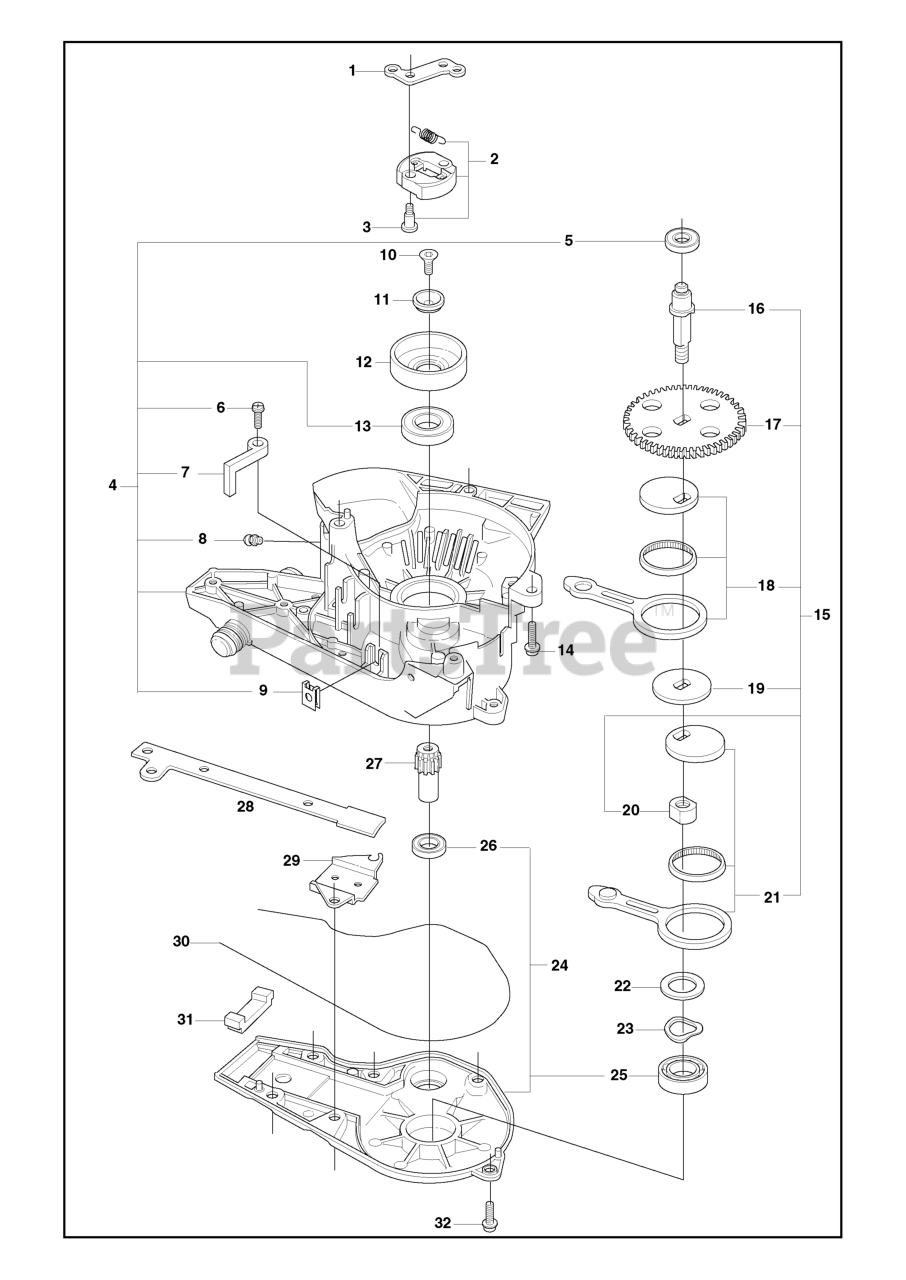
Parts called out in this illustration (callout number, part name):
1	CLUTCH YOKE
2	CLUTCH CPL
3	GEAR HOUSING
4	BALL BEARING
7	GREASE NIPPLE
11	CLUTCH DRUM
12	BALL BEARING 6002-2RS1
18	CONNECTING ROD
21	CONNECTING ROD
22	WASHER 15X24
